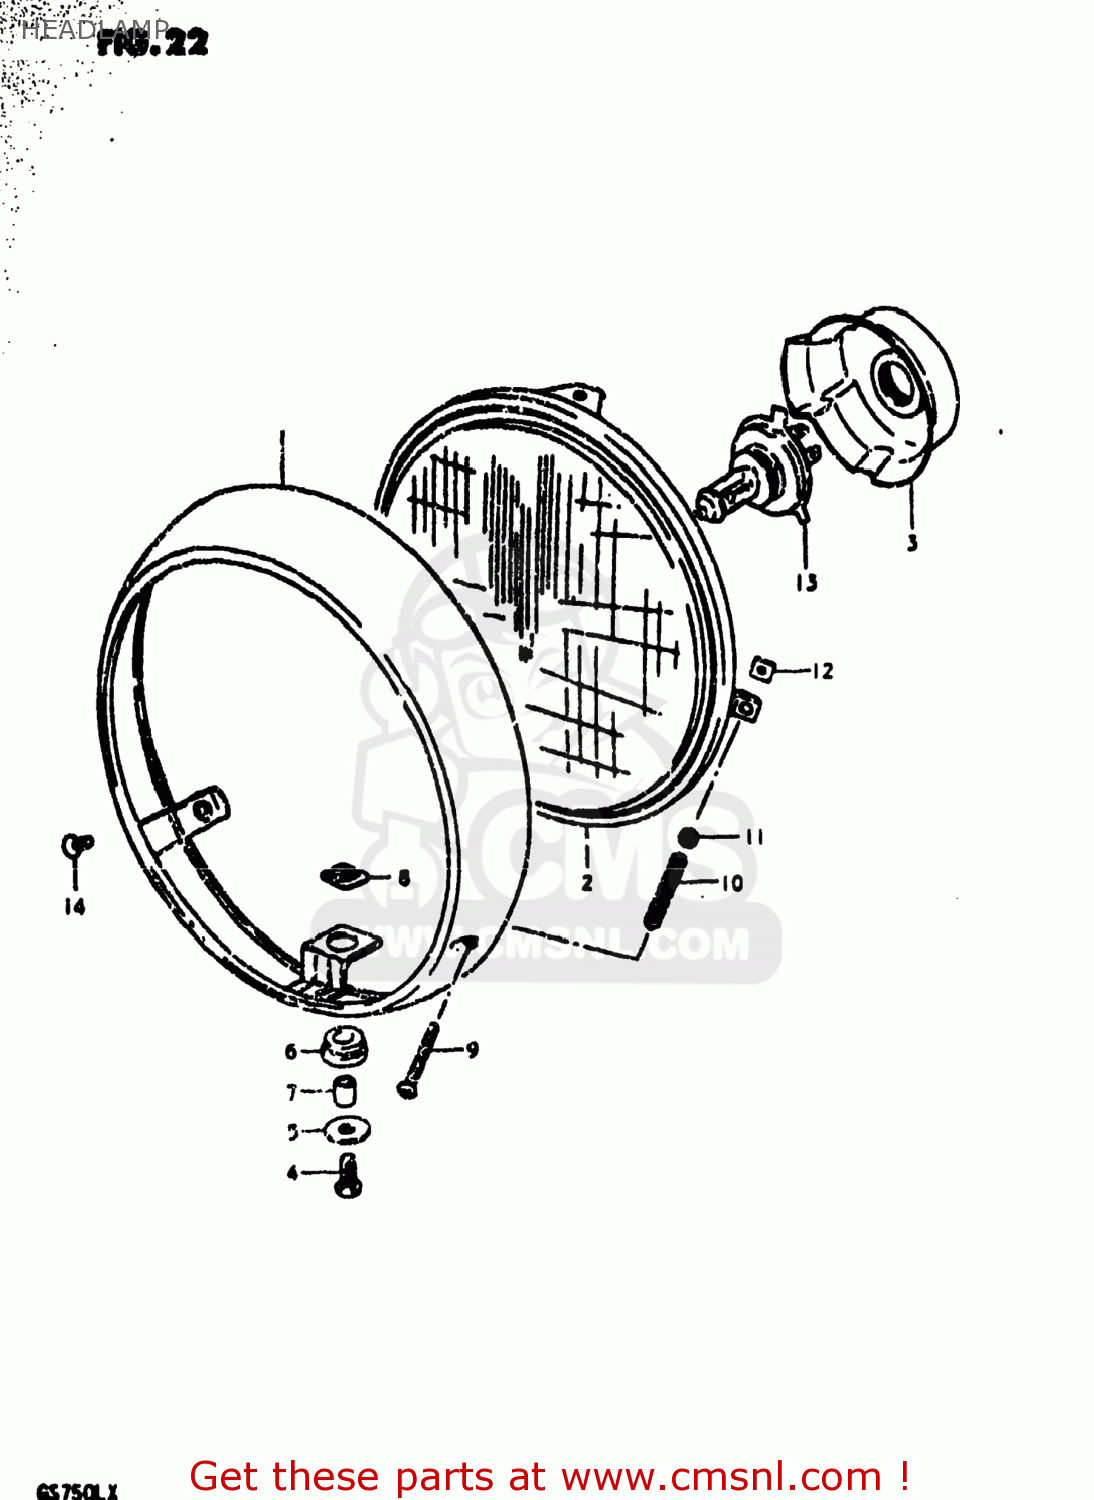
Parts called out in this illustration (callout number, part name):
1	RIM
2	LAMP UNIT
3	COVER,SOCKET
4	SCREW
5	WASHER
6	CUSHION
7	SPACER
8	NUT
9	SCREW
10	SPRING,HEADLAMP ADJUST
11	WASHER
12	NUT,HEADLAMP ADJUSTER
13	BULB(12V60/55W,H4)
14	SCREW
